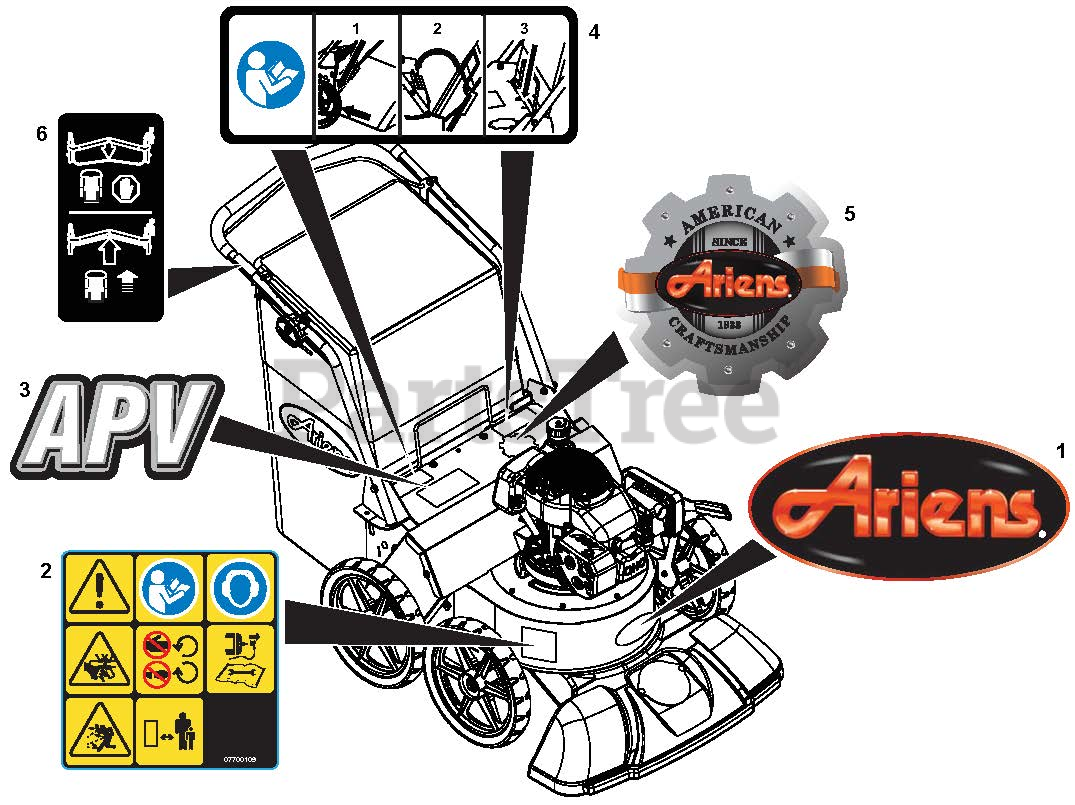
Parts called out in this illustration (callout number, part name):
1	DECAL, ARIENS JEWEL (LARGE)
2	DECAL,VAC WARNING ISO
3	DECAL - APV
4	DECAL, APV BAG INSTALLATION
5	DECAL, ARIENS HERITAGE - LARGE
6	DECAL, DRIVE CONTROL
